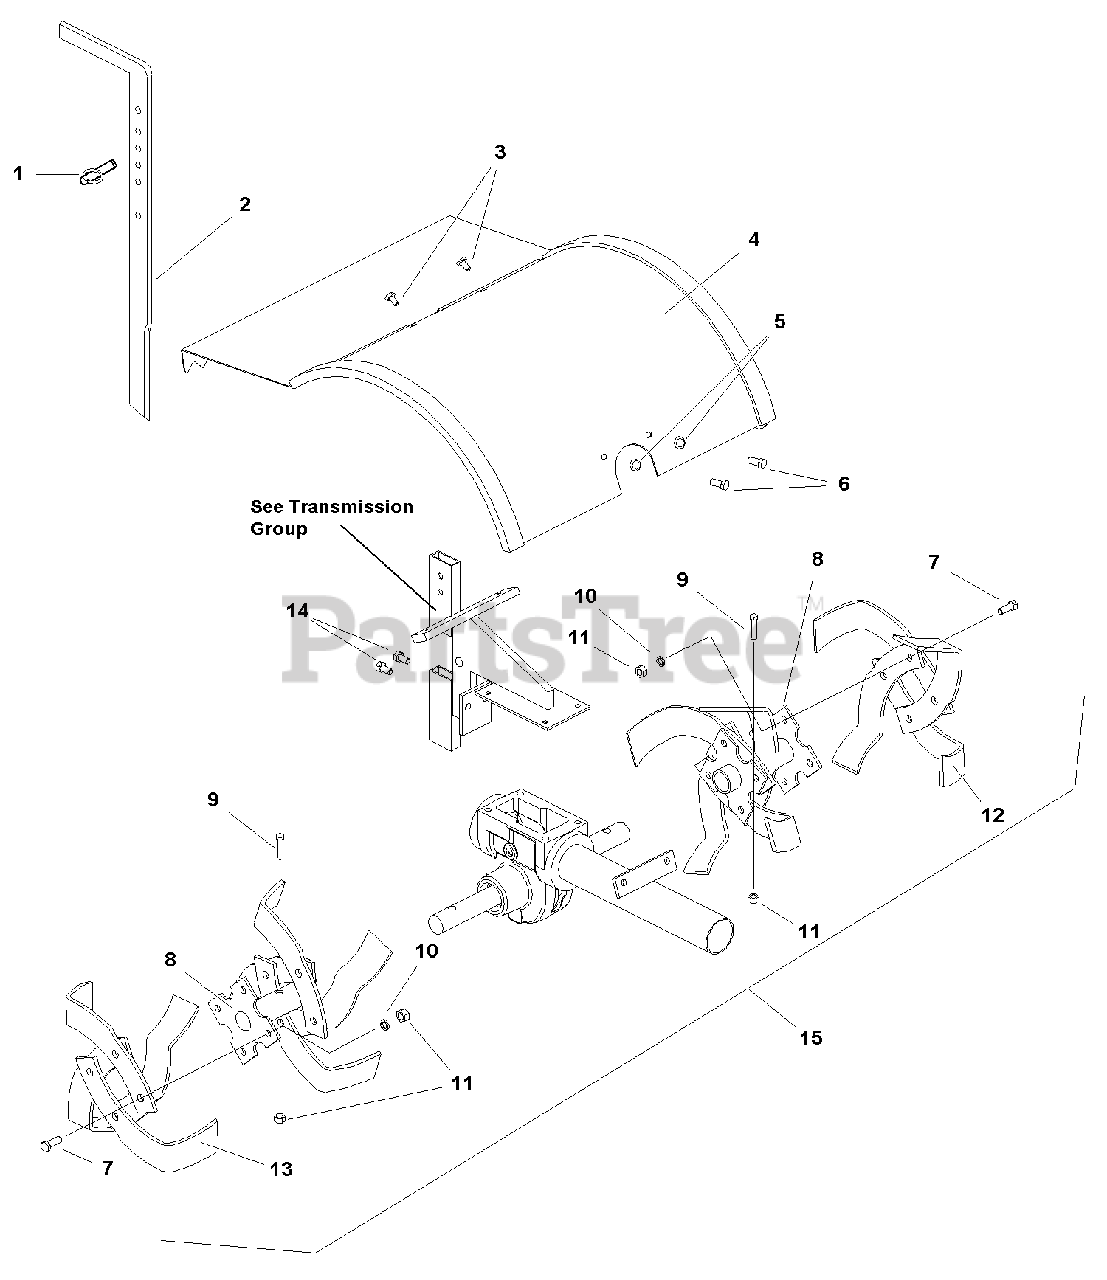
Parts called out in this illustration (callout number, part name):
1	PIN, DETENT 5/16
2	LEVER, Depth Regulator
3	CAPSCREW, Hex Head, 1/4-20 x 1/2
4	HOOD, Tiller, No Decal
5	LOCKWASHER, 5/16
6	CAPSCREW, Hex Head, 5/16-18 x 1/2
7	CAPSCREW, Hex Head, 3/8-16 x 1
8	HOLDER, Tine Blade Left and Right
9	CAPSCREW, Hex Head, 3/8-16 x 1-3/4
10	LOCKWASHER, 3/8
11	NUT, Hex Centerlock, 3/8-16
12	TINE BLADE, Left Side
13	TINE BLADE, Right Side
14	BOLT, Hex Flange Head, 5/16-18 x 1/2
15	REPL KIT, Tine Blade Holder (Includes Reference Nos. 7, 8, 9, 10, 11, 12, and 13)
